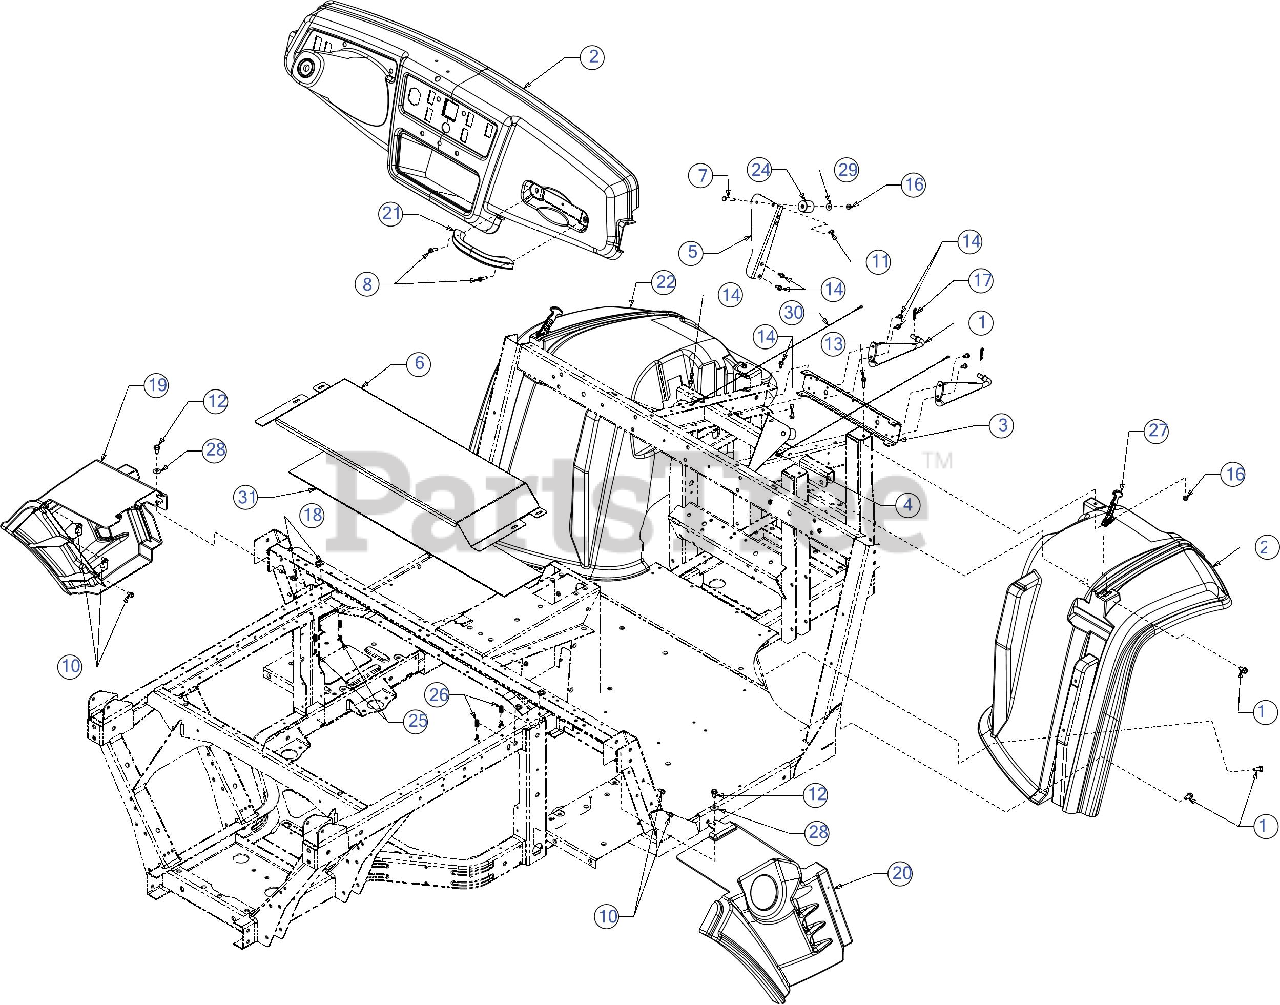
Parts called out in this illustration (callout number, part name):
1	HOOD MOUNT ROD ASSEMBLY
2	DASH ASSEMBLY
3	FRAME CROSS CHANNEL
4	HOOD & DASH BRACKET (RH)
5	HOOD & DASH BRACKET (LH)
7	HEX SCREW 1/4-20 x 1.75
8	MACHINE SCREW 1/4-20:1
10	HEX SCREW 1/4-15 x .50
11	HEX SCREW #12-16 x .50
12	SCREW 5/16-18 x .750
13	SCREW 1/4-20 x 1.0
14	SCREW 1/4-20 X.500
16	FLANGE LOCK NUT
17	INTERNAL COTTER PIN
18	1/4 TURN PANEL HANDLE
19	LOWER FENDER (LH)
20	LOWER FENDER (RH)
21	GRAB HANDLE
22	UV FENDER (LH)
23	UV FENDER (RH)
24	HOOD LATCH ROLLER
25	SPRING CLIP
26	COMPRESSION SPRING
27	HOOD STRAP
28	BELL WASHER .337 X.867 x .057
29	FLAT WASHER .283 ID x .749 x .030
30	HOOD CABLE
31	INSULATION
